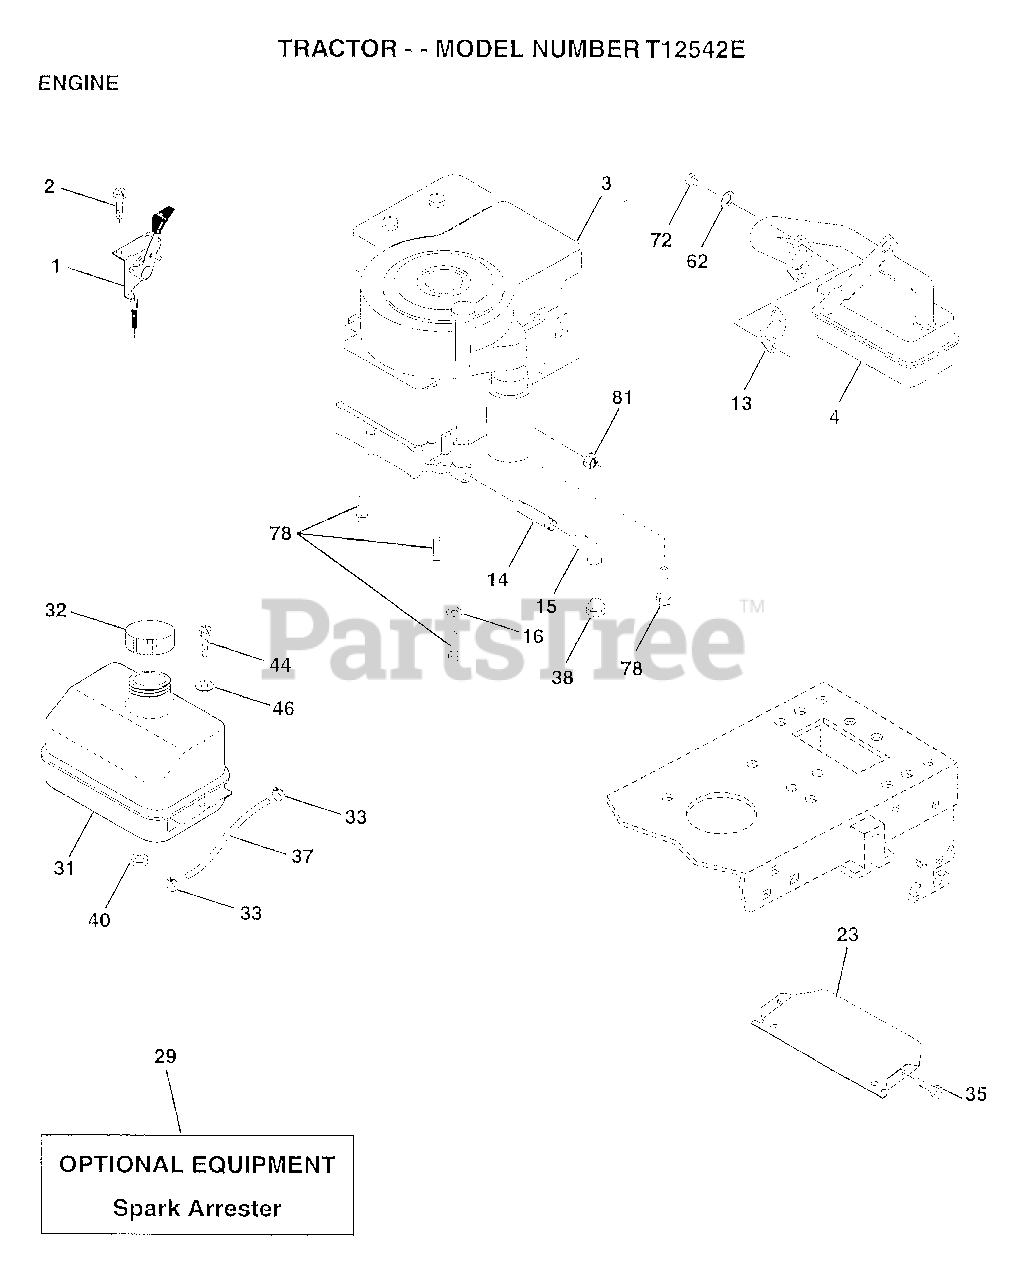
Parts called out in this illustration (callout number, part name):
1	CONTROL THROTTLE
2	SCREW LT
4	MUFFLER
13	GASKET ENG 1 313 LD TIN PLATED
14	PIPE NIPPLE
15	ELBOW
16	LOCKWASHER
23	SHIELD-HEAT
31	TANK.FUEL.LT.
32	CAP ASM FUEL
33	HOSE CLAMP
35	SCREW
37	LINE FUEL
44	SCREW HEX CRT
46	WASHER
62	LOCKWASHER
72	SCREW
78	SCREW
81	NUT
